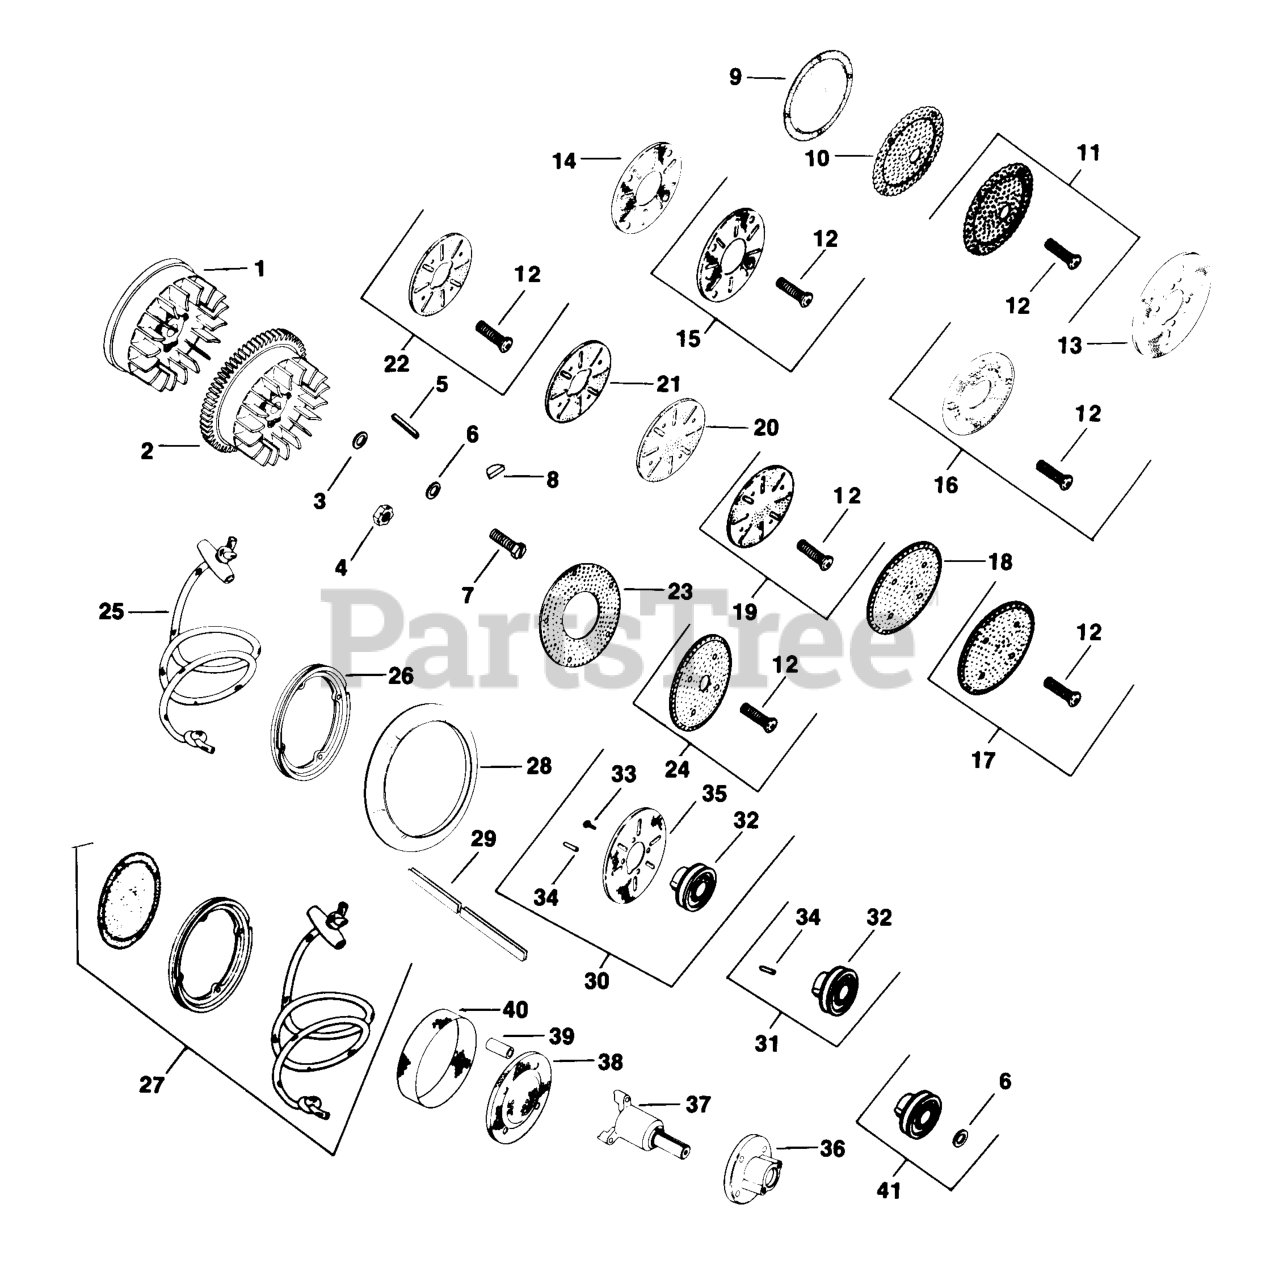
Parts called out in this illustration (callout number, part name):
2	FLYWHEEL - DISCONTINUED
3	WASHER - DISCONTINUED
4	NUT - USE 25 100 02
5	KEY - DISCONTINUED
6	WASHER - USE 52 468 15
7	SCREW - USE 25 086 24
8	KEY, 3/16" X 1"
12	SCREW, POZ TRS HD 1/4-20X5/8" - DISCONTINUED
19	KIT, GRASS SCREEN - (#DSC)
25	ROPE-DISCONTINUED
